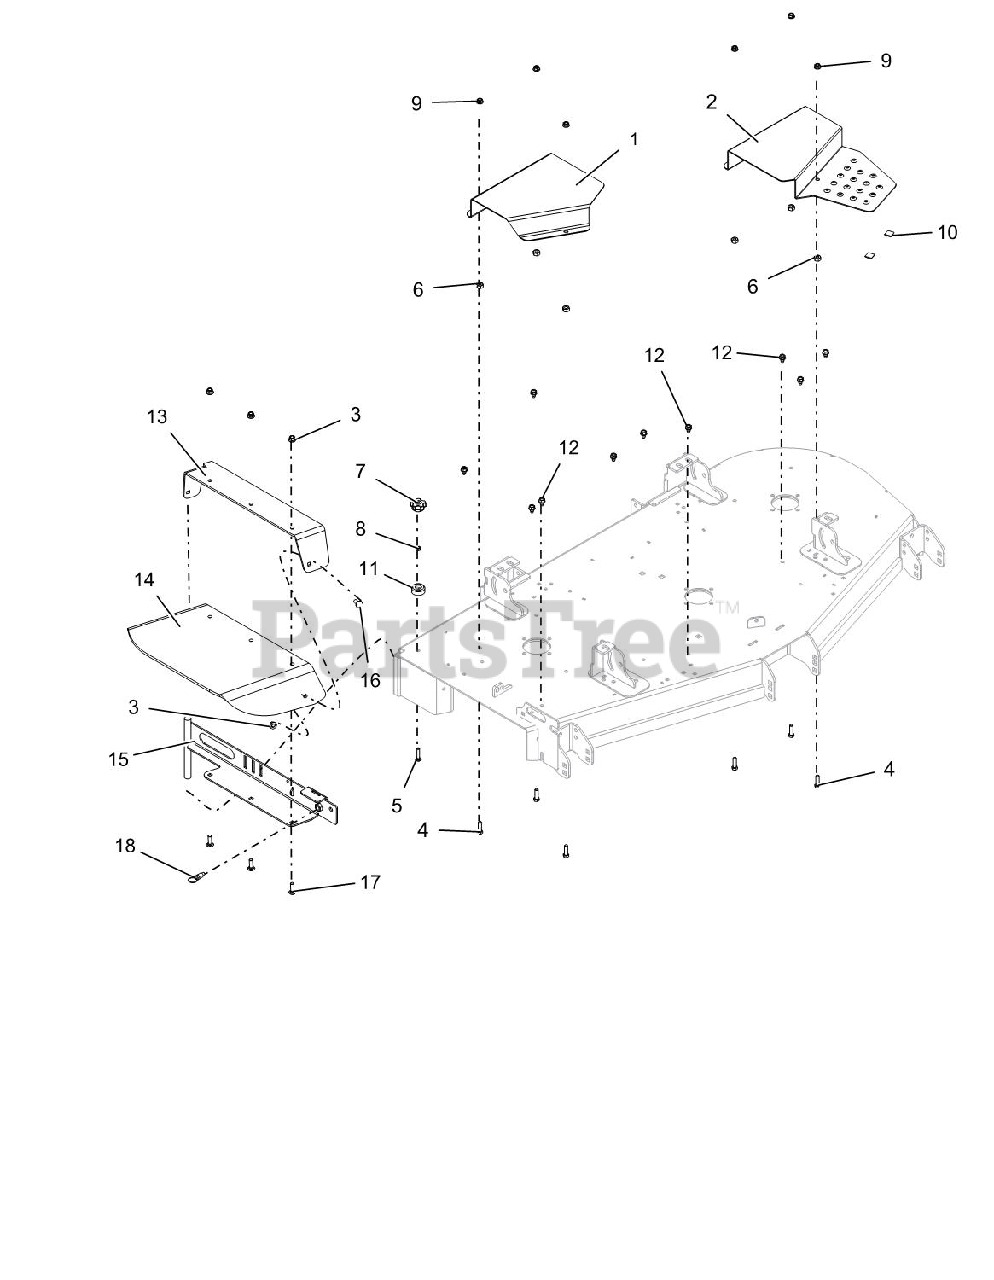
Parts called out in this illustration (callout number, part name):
1	GUARD, 60"-66" RH DECK BELT-RED
2	GUARD, 60" LH DECK BELT-W/STEP-RED
3	NUT-LK-NYL-FLG .38-16 YWZC
4	BLT-HEX .38-16X1.25 GR5 YWZC
5	BLT-RDHDSQNK .31-18X1.50 G5 YWZC
6	NUT-HEAVY HEX .38-16 YWZC
7	KNOB, CLAMPING
8	NUT-LK-CTR .31-18 YWZC
9	@NUT-SPNLK-FLG .375-16 YWZC
11	BUMPER, RECESSED 1.50 X .63 W/.31 HOLE
12	SCR-TAP .38-16X.50 HWH TR YWZ
13	DISCHARGE CHUTE SUPPORT W/SAFETY DECAL-RED
14	CHUTE, RUBBER DISCHARGE
15	WLDMT, 52"-60" DISCH CHUTE MTG-RED
16	BLT-RDHDSQNK .38-16X1.00 G5 YWZC
17	BLT-RDHDSQNK .38-16X1.25 G5 YWZC
18	PULL PIN,.50-13THDX.310 PLNGR
